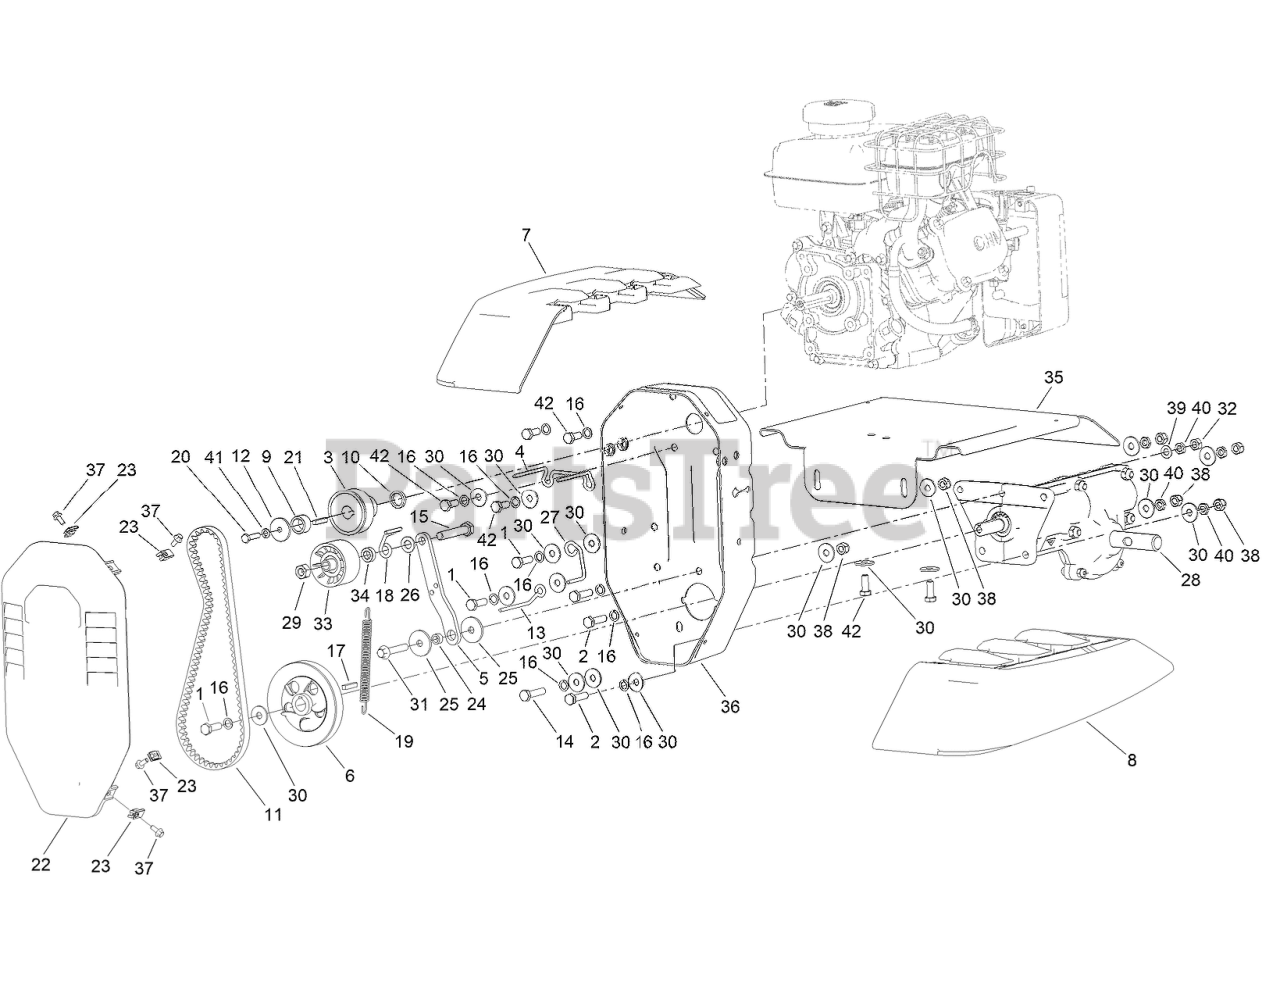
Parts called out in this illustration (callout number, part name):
1	SCREW-HHCS
2	SCREW-HHCS
3	PULLEY-16MM
4	BELT GUIDE-DOUBLE
6	PULLEY-TRANSMISSION
7	SHIELD-LEFT
8	SHIELD-RIGHT
9	BUSHING
10	BUSHING
12	WASHER-FLAT
13	BELT GUIDE-SINGLE
14	SCREW-HHCS
15	SCREW-HHCS
16	WASHER-LOCK
17	KEY-SQUARE
18	BELT CATCH
19	TENSION SPRING
20	SCREW-HHCS
21	KEY-SQUARE
22	COVER-PULLEY
23	CAGE NUT
24	BUSHING
25	WASHER-WIDE
26	WASHER-PLAIN
27	GUIDE-BELT
28	MOUNT-TRANSMISSION
29	NUT-HEX
30	WASHER-FLAT
31	SCREW-HHF
32	NUT-HEX
33	PULLEY-IDLER
34	SPACER-18MM
35	SHIELD-CENTER
36	BOX-PULLEY
37	SCREW-HHF
38	NUT-HEX
39	WASHER-FLAT
41	WASHER-LOCK
42	SCREW-HHCS
